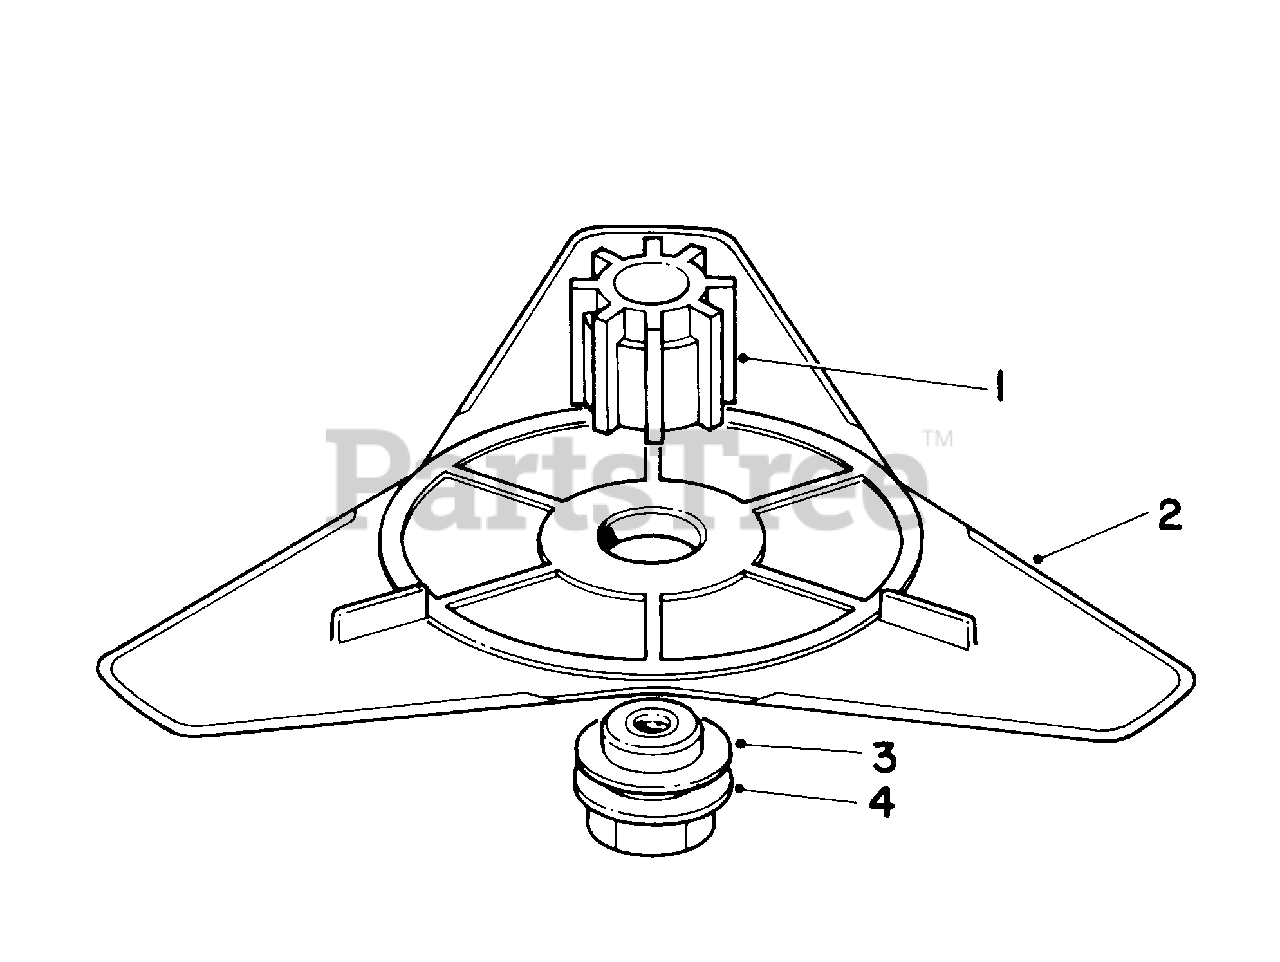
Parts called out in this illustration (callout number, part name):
1	Adapter-Blade
2	Blade-Flex
4	Nut-Adapter
